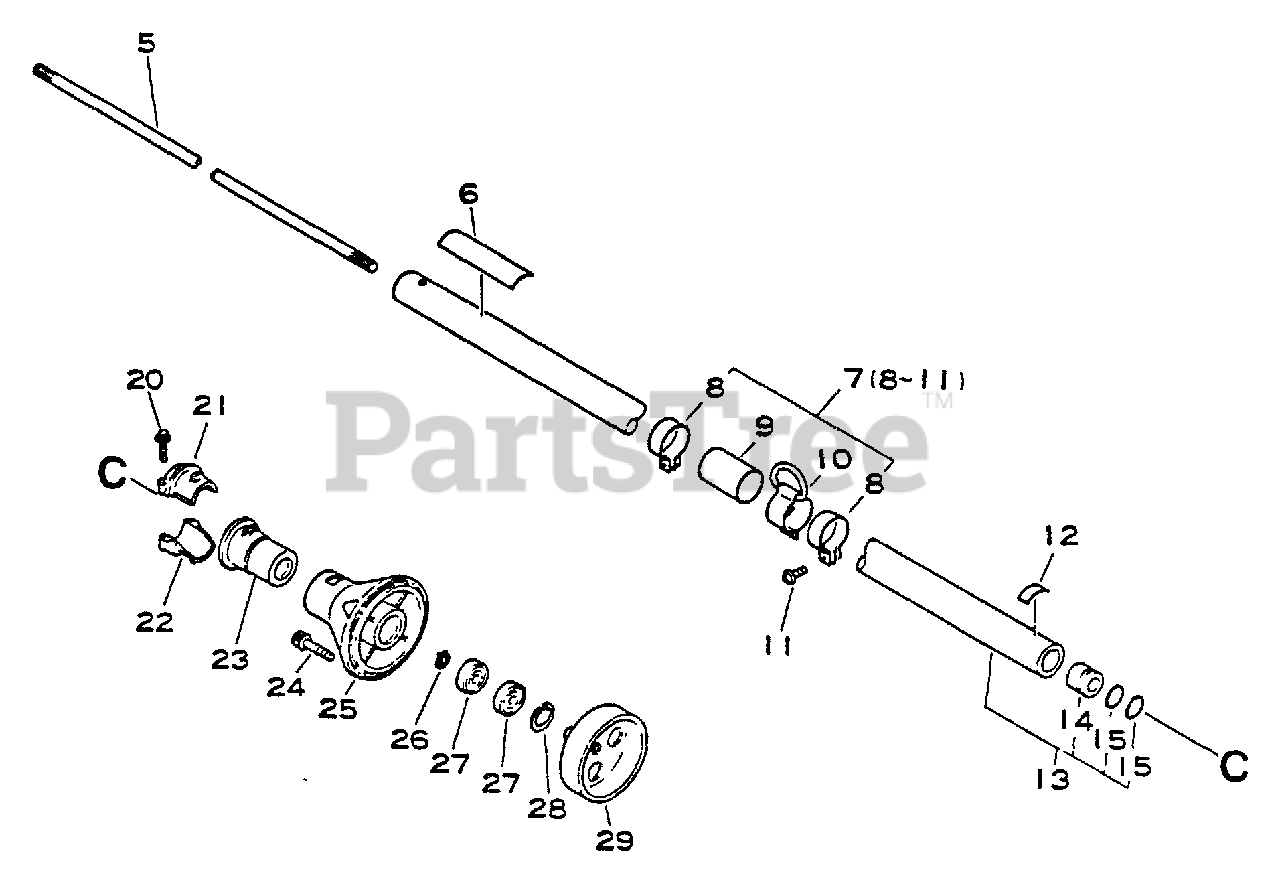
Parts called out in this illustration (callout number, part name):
5	DRIVESHAFT - SOLID
6	LABEL - CAUTION
7	HANGER KIT
8	HOOK
9	COLLAR
10	HOOK
11	SCREW - 5X14
12	LABEL - ALIGNMENT
13	MAIN PIPE ASSY
15	O-RING - 20
20	BOLT - 5X25
21	CLAMP, MAIN PIPE
22	CLAMP, MAIN PIPE
24	SCREW - 5X20
25	FLANGE, DRIVESHAFT
26	RING, RETAINING - 12
27	BEARING, BALL - 6001 DDU
28	RING, RETAINING - 28
29	DRUM, CLUTCH
